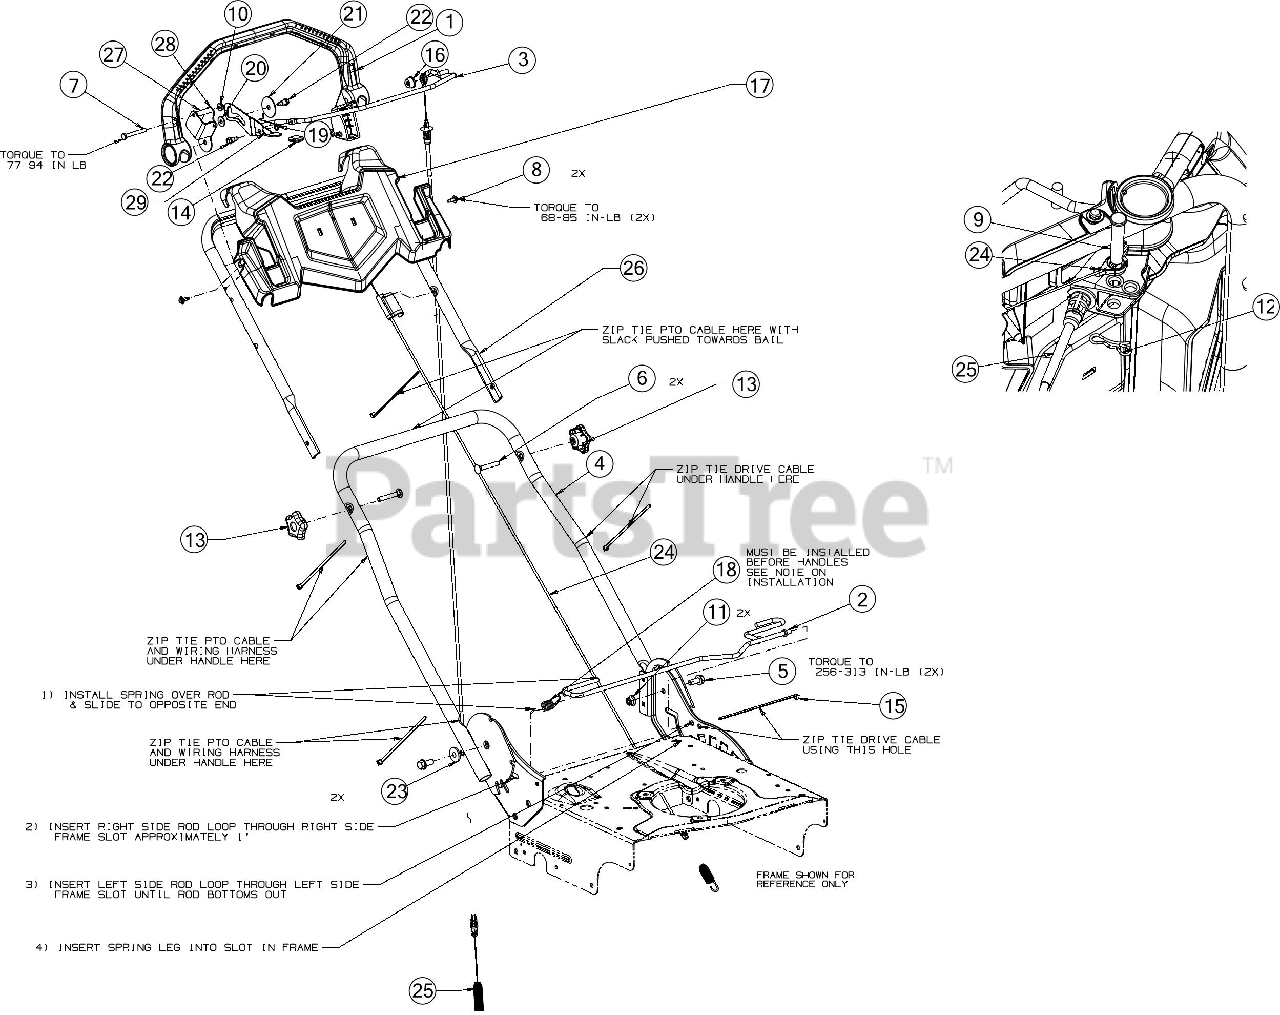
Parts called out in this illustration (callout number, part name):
1	DRIVE HANDLE ASSEMBLY (BLACK)
2	HANDLE PIVOT
3	PTO STRAIGHT HANDLE BAIL
4	LOWER HANDLE ASSEMBLY
5	SCREW 3/8-16 x .875 GR5
6	CARRIAGE BOLT 5/16-18 x 2.00 GR5
7	SCREW 1/4-20 x 2 GR5
8	SCREW M6-1 x .625
9	CLEVIS PIN 3/8 x 1.87
10	FLANGE LOCK NUT
12	BOW TIE COTTER PIN 1/4-5/16
13	STAR KNOB 5/16-18
15	7" CABLE TIE
16	PUSH CAP 0.3125
17	HANDLE CONSOLE
18	TORSION SPRING .48 x .177
19	TORSION SPRING
20	FLAT WASHER .28 ID x .74 OD x .063
21	FLAT WASHER .350X1.59X.062
22	SHOULDER SCREW
23	SHOULDER SPACER .625 x .169
24	DRIVE CABLE
25	CONTROL CABLE
26	UPPER HANDLE
27	SPACER:.260 x .372 x 1.420
28	MAIN LOCK OUT PLATE BRACKET
29	LOCK OUT BRACKET
